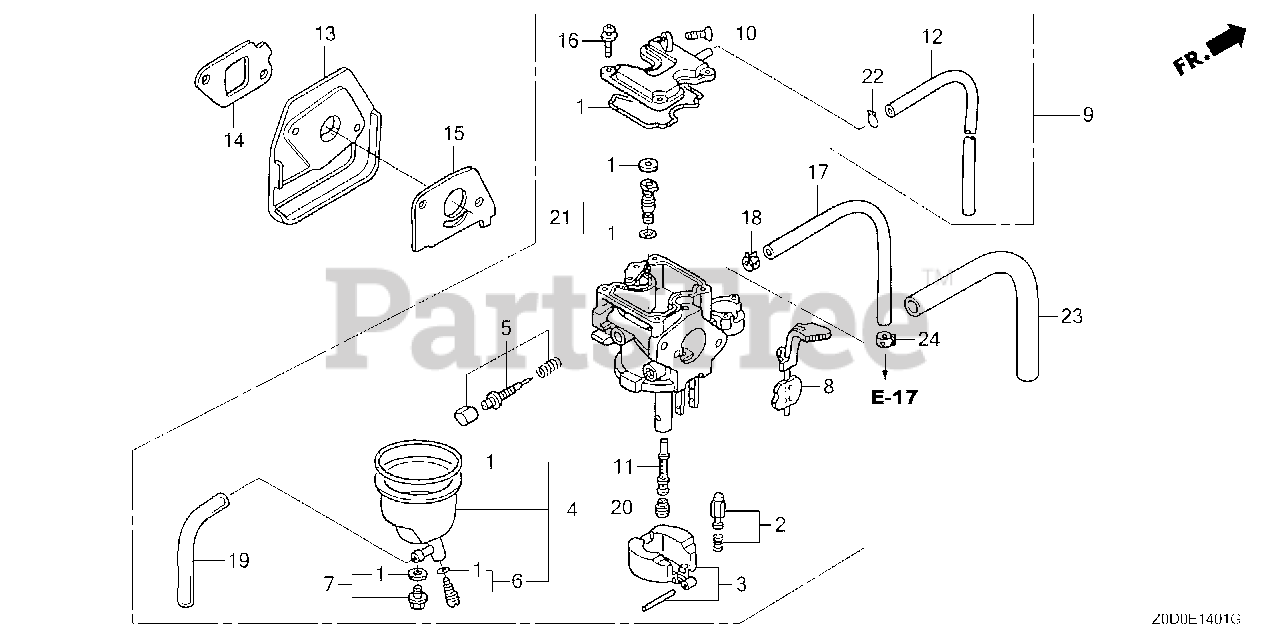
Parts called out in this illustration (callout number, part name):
1	GASKET SET
2	VALVE SET, FLOAT (SEAT NOT INCLUDED)
4	CHAMBER SET, FLOAT (CARBURETOR NO.)
6	SCREW SET, DRAIN
7	SCREW SET (CARBURETOR NO.)
8	LEVER SET, CHOKE
9	CARBURETOR ASSY. (BF33D C)
10	SCREW, THROTTLE STOP
11	NOZZLE, MAIN
12	TUBE, AIR VENT
13	INSULATOR, CARBURETOR
14	GASKET, INSULATOR
15	GASKET, CARBURETOR
16	SCREW-WASHER (4X12)
18	CLAMP, TUBE (D8.5)
19	BULK HOSE, VINYL (3.5X6.5X8000) (3.5X6.5X100)
20	JET, MAIN (#55)
20	JET, MAIN (#58)
20	JET, MAIN (#60)
21	JET SET, PILOT (#35)
22	CLIP, TUBE (B1 8)
24	CLAMP, TUBE (D8.5)
